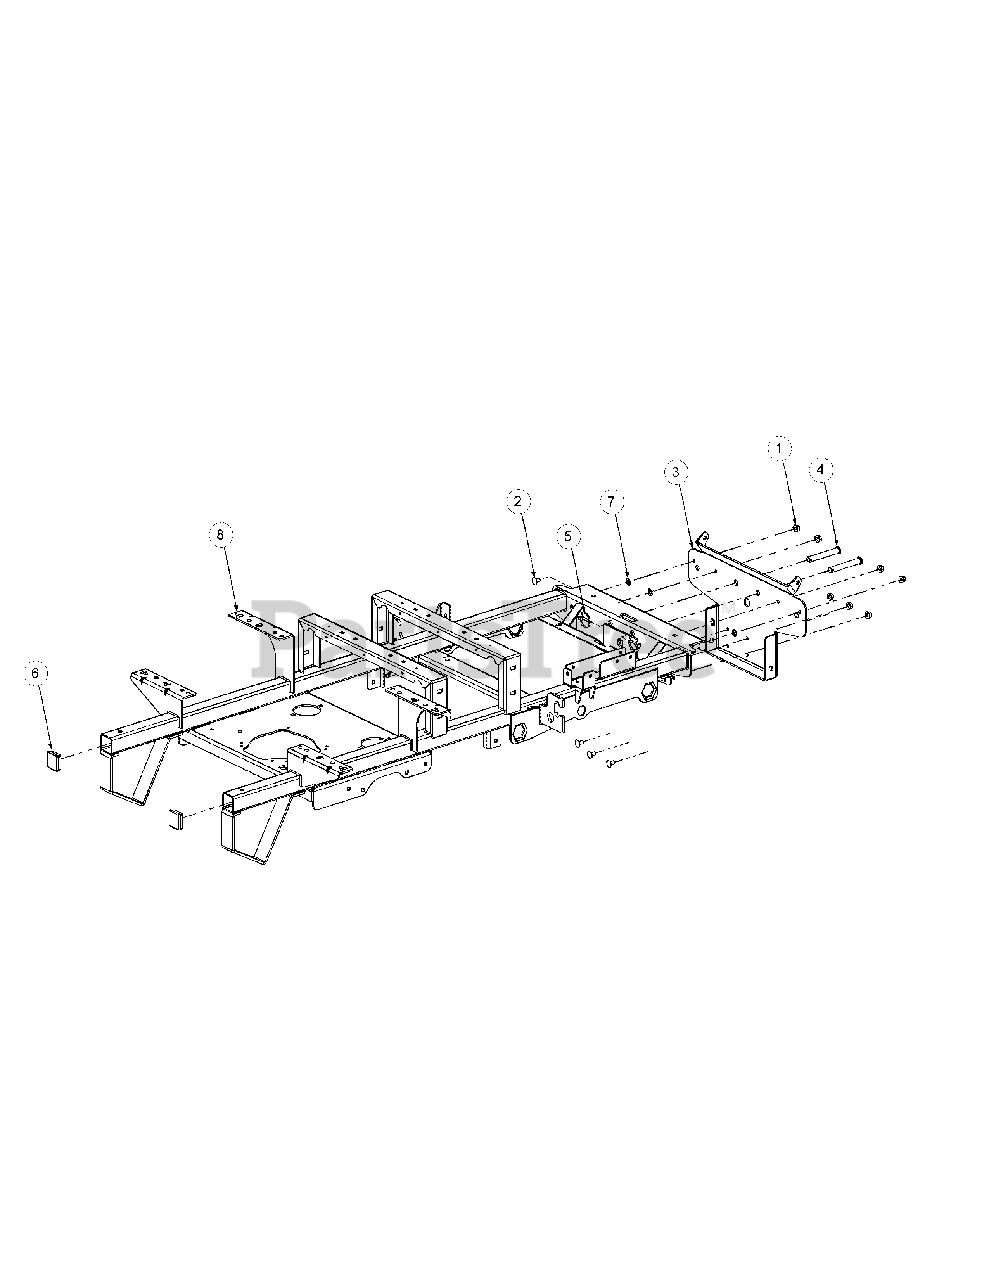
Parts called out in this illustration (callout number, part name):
1	Hex Nut, 3/8-16 Flange Lock
2	Carriage Bolt, 3/8-16 x .75 Long
3	Bracket Assembly, Frame, Front
4	Clevis Pin, .625 Dia x 4.375 Long
5	Linch Pin, 3/16 Dia.
6	Plug, Square Tube
7	Push Retainer, 3/8
8	Frame Assembly
